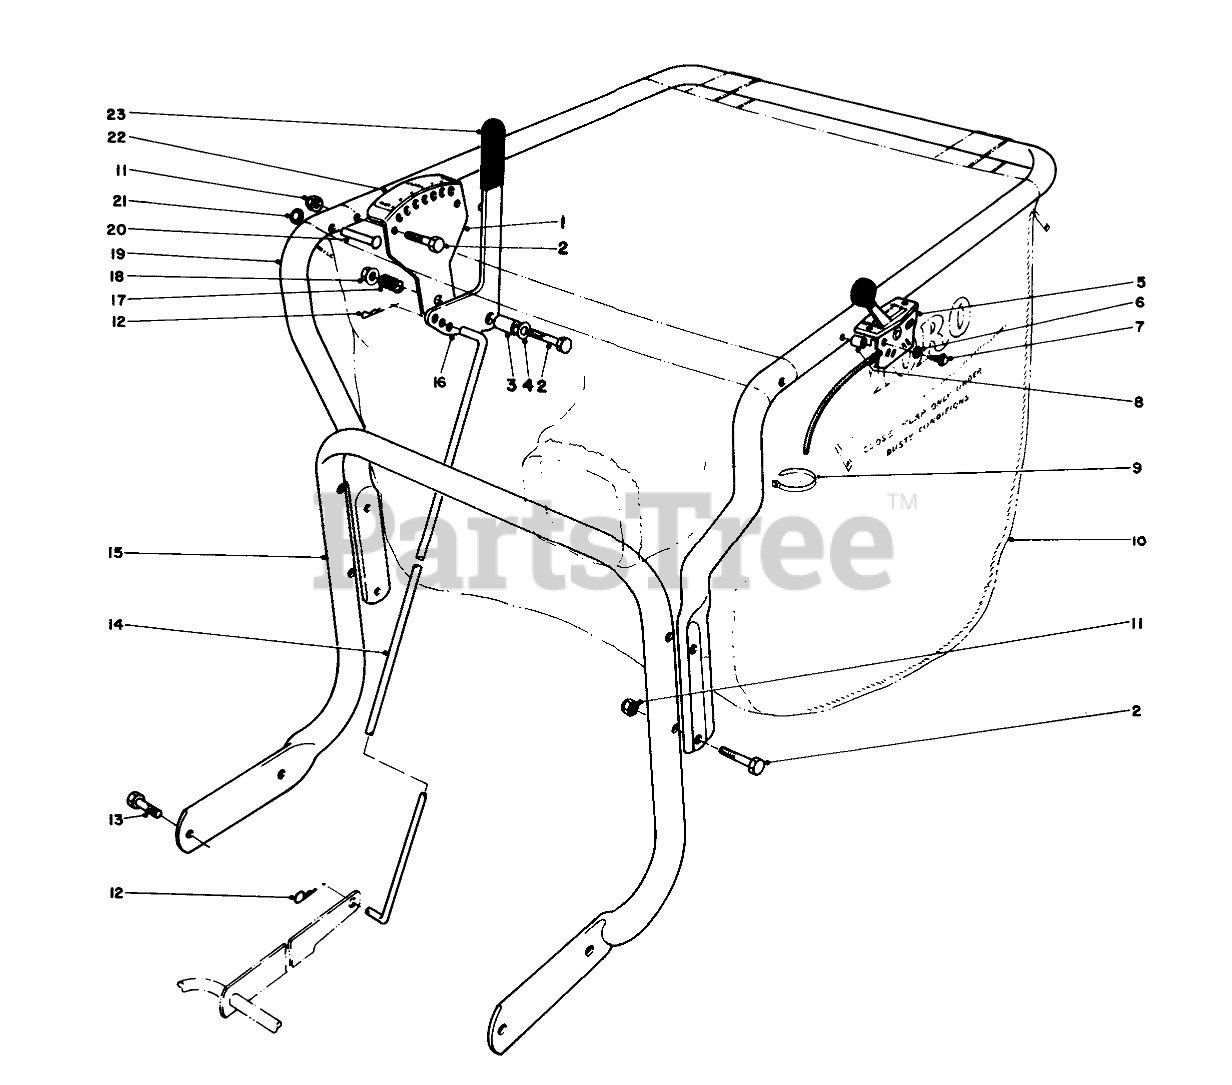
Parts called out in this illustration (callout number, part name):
1	Adjustment Bracket
2	SCREW-HH
3	SPACER
4	WASHER-FLAT
5	THROTTLE CONTROL
6	WASHER-LOCK, EXT
7	10-24 X 1 PAN HD SCR
8	SPACER
9	TIE-CABLE
10	Bag-Vacuum
11	NUT-LOCK, CONE
12	PIN-COTTER
13	SCREW-HH
14	HEIGHT ADJ. ROD
15	HANDLE
16	Handle-Adjustment
17	SPRING-COMPRESSION
18	NUT-HF
19	HANDLE-UPPER, VACUUM
20	RIVET
21	NUT-PUSH IN
22	HT ADJ DECAL
23	GRIP-HANDLE
